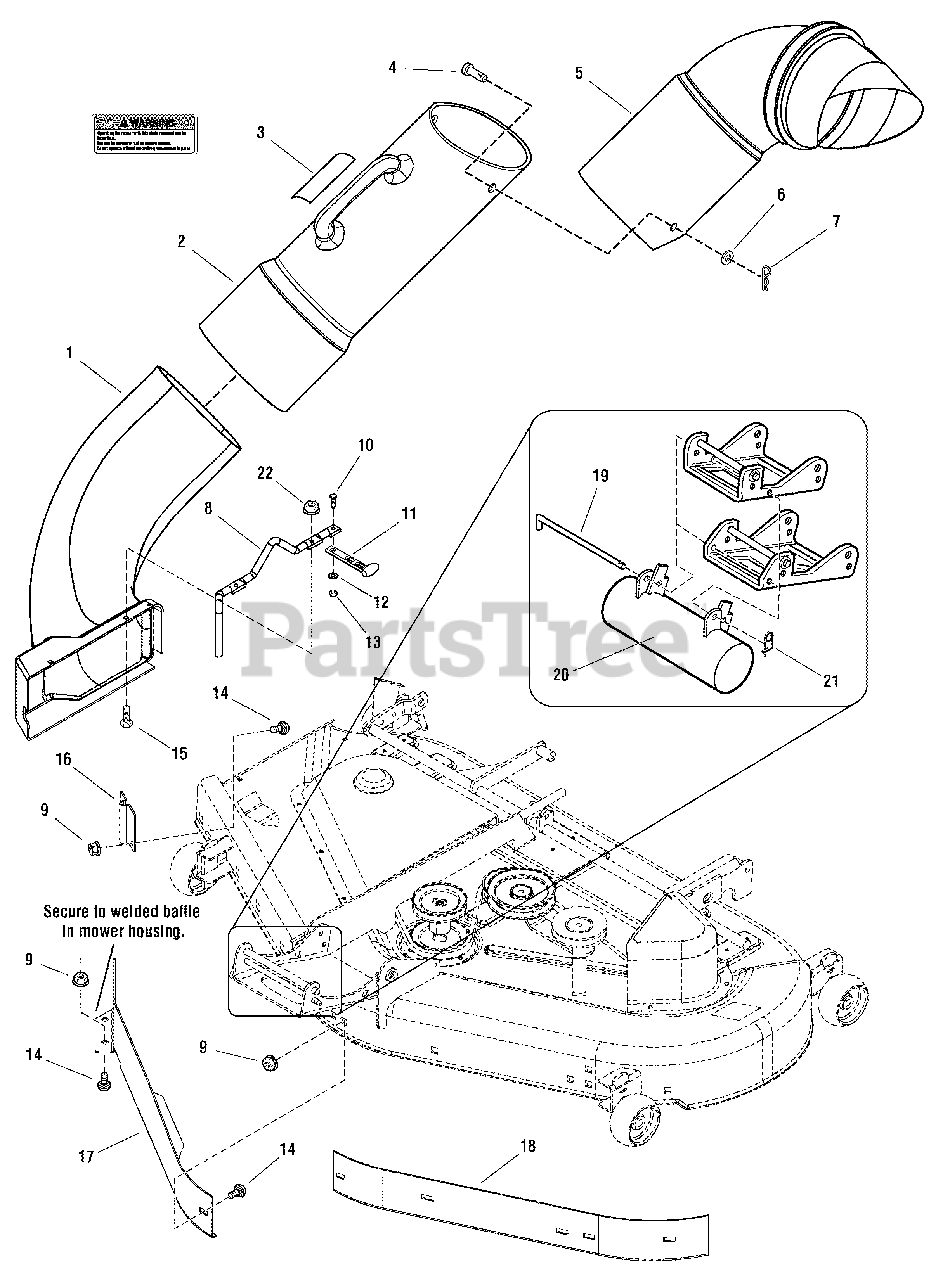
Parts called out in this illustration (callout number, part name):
1	ADAPTER, Lower Chute
2	CHUTE, Grass Catcher Middle
3	DECAL, Warning Operating Mower Without Chute
4	PIN, Round Head Drilled, 1/2 x 1
5	CHUTE, Grass Catcher Upper Elbow
6	WASHER, 1/2
7	CLIP, Hair Pin, Spring Wire
8	ROD, Chute Mounting
9	NUT, Hex Flange Whiz Lock, 5/16-18
10	SCREW, Pan Head Phillips, #10-24 x 1
11	STRAP, Black Rubber, 4-13/16 Long
12	WASHER, 3/16
13	NUT, Hex Lock with Nylon Insert, 10-24 NC3B
14	CARRIAGE BOLT, Hex Head, 5/16-18 x 5/8 G5
15	CAPSCREW, Heax Head, 5/16-18 x 7/8 G5
16	PLATE, Chute Rod Mounting
17	BAFFLE, Blowout RH, 44"
17	BAFFLE, Blowout RH, 50"
18	BAFFLE, Blowout LH, 44"
18	BAFFLE, Blowout LH, 50"
19	ROD, Weight Retainer, 3/8 x 9-21/64
20	WEIGHT ASSEMBLY, Front Counter
21	CLIP, Spring Pin
22	NUT, ESNA Flange
